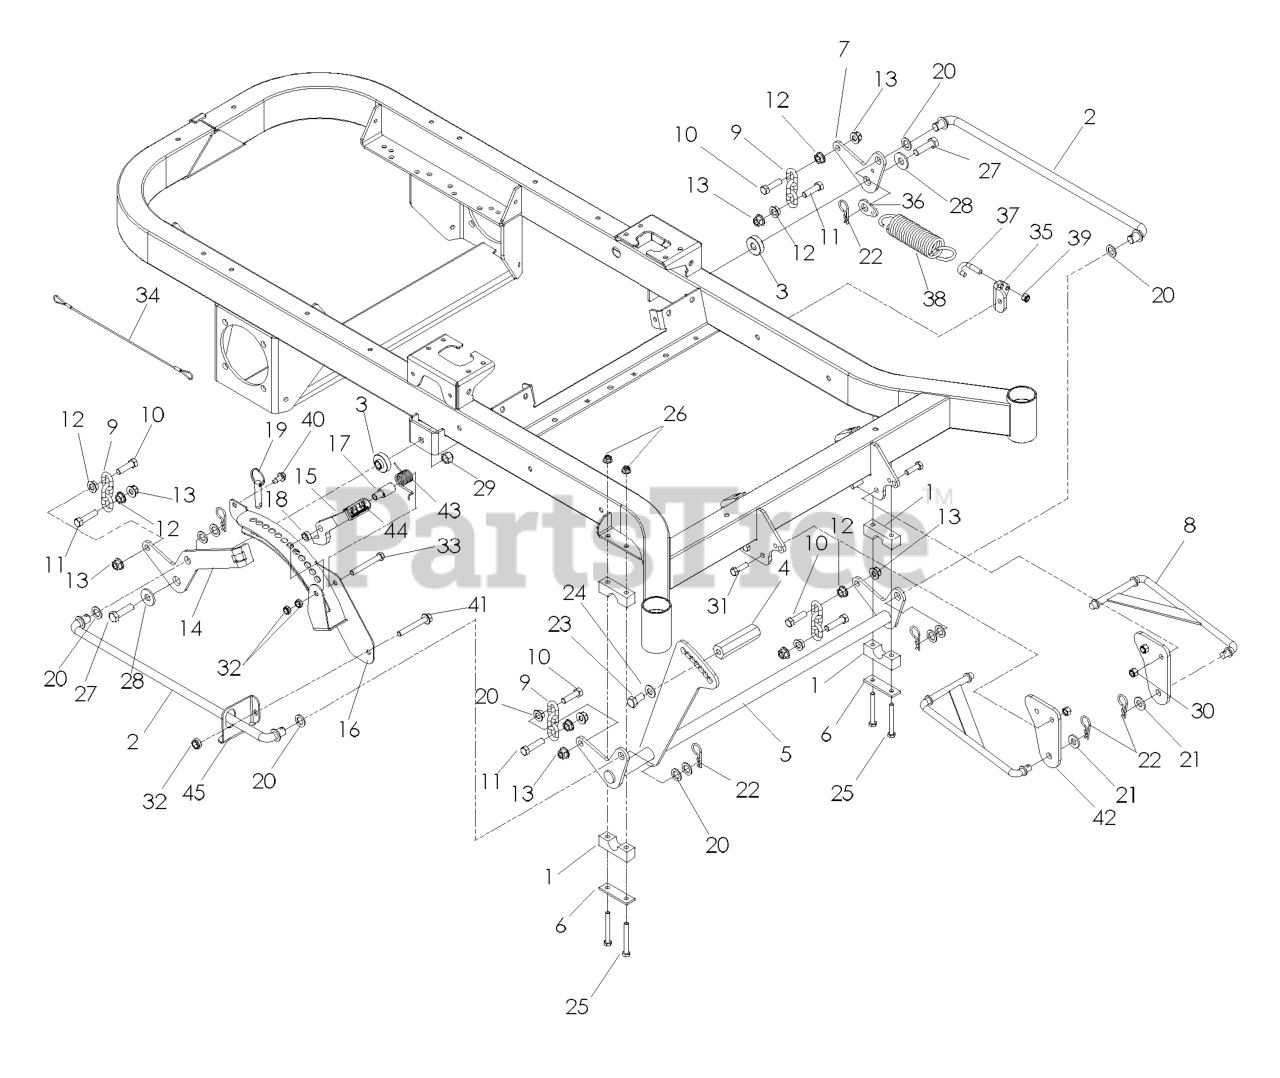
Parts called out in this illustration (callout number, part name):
1	PILLOW BLOCK
2	CROSS LINK
3	IDLER SPACER
4	PEDAL, FOOT, HEX
5	SHAFT, FRONT-LIFT
6	REINFORCEMENT BAR
7	BELLCRANK, RR, LIFT
8	STRUT LINKAGE
9	LIFT CHAIN - 3 LINK
10	HCS 7/16C X 1 1/2
11	HCS 7/16 - 14 X 1 3/4
12	NUT 7/16C WHIZ
13	NUT 7/16-14 HEX WHIZ LK
14	BELLCRANK, RR, RT
15	LATCH, TRANSPORT
16	HEIGHT, ADJUST, DECK
17	PIVOT, LATCH, TRANSPORT
18	SPACER, .3
19	PIN, 1/2 X 1 1/2, DETENT RING
20	BUSHING
21	WASHER 1/2" FLAT
22	PIN, COTTER 1 3/4
23	HHCS 1/2-13 X 1
24	WASHER, 7/16 DISC SPRING
25	HCS 5/16C X 2-3/4
26	5/16-18 NYLOC FLANGE NUT
27	HCS 1/2-13 X 1 3/4 GR 8
28	WASH USS FLAT 1/2
29	NUT 1/2-13 HEX NYLOC ZD
30	NUT 3/8-16 NYLOC
31	HCS 3/8C X 1 1/4 GR5
32	NUT HEX 3/8-16 NYLON, THIN
33	HCS 3/8C X 3
35	MOUNT, SPRING
36	TAB, SPRING
37	J-BOLT
39	NUT 5/16 NYLOC
40	BOLT 5/16-18 X 3/4
41	HHFS 3/8-16 X 2 3/4
42	MOUNT, STRUT
43	SPRING, TORSION
44	GRIP, TRANSPORT-RELEASE
45	SUPPORT, LIFT ROD
